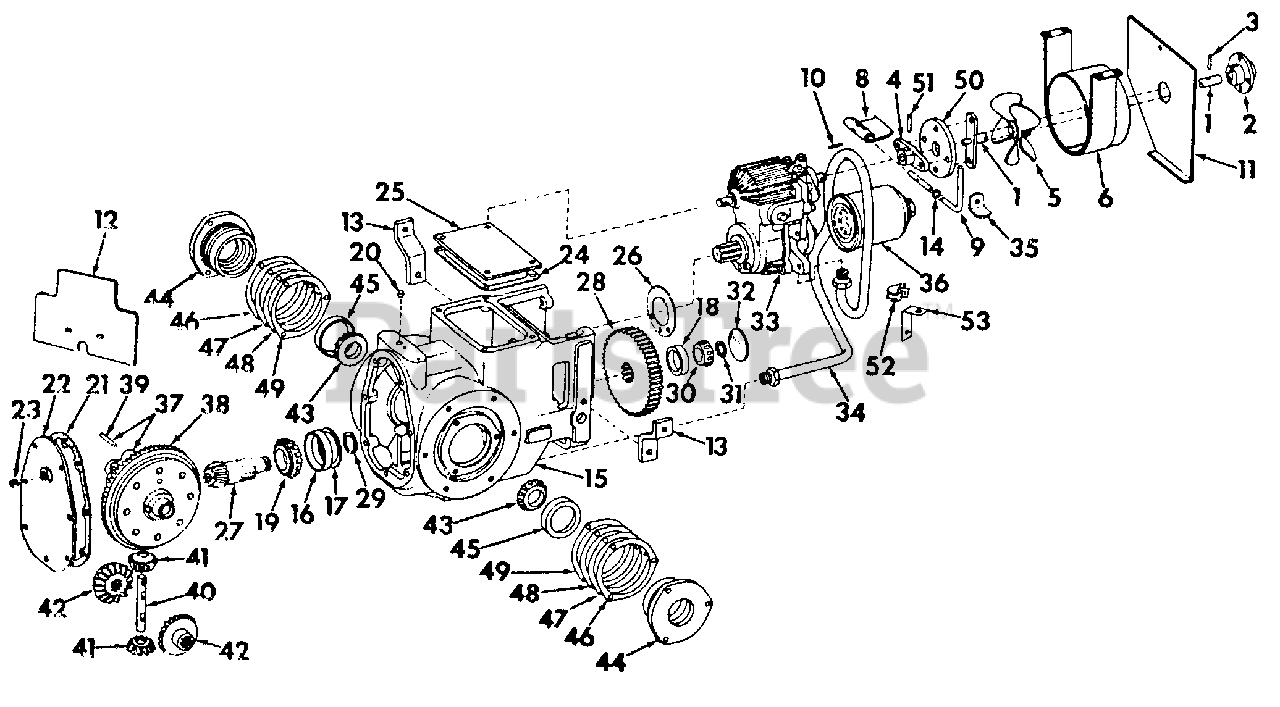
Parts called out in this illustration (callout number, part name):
1	Rod Assy, Drive
2	Hub Assy, Drive Plate
3	Pin, 1/4 X 1-1/2 Dowel
4	Arm, Coupling
6	Shroud Assy, Fan
8	Actuator, Dump Valve
9	Rod, Dump Valve
10	Pin, 1/8 X 3/4 C-Z Hv Coiled Spring
11	Plate, Air Baffle
12	Shield, Transmission Case Rear Cover
13	Bracket, Transmission Mounting
14	Grommet, Dump Valve Rod
15	Case Assy, Transmission
16	Bearing, Bevel Pinion Shaft Rear Cup
17	Shim, Rear Brg Cup, .004
18	Bearing, Bevel Pinion Shaft Front Cup
19	Bearing Assy, Bevel Pinion Shaft Rear Cone
20	Plug, Transmission Breather
21	Gasket, Transmission Case Rear Cover Plate
22	Plate Assy, Transmission Case Rear Cover
23	Plug, 1/2-14 Automotive Sq-Soc-Hd Drain
24	Gasket, Transmission Case Top Cover
25	Cover, Transmission Case Top
26	Gasket, Transmission Case Front
27	Shaft, Bevel Pinion
28	Gear, Constant Mesh-66T
29	Ring, Gear Retaining
30	Bearing Assy, Bevel Pinion Shaft Front Cone
31	Ring, Pinion Shaft Front Brg Retainer, .125
31	Ring, Pinion Shaft Front Brg Retainer, .119
31	Ring, Pinion Shaft Front Brg Retainer, .113
31	Ring, Pinion Shaft Front Brg Retainer, .107
31	Ring, Pinion Shaft Front Brg Retainer, .101
31	Ring, Pinion Shaft Front Brg Retainer, .131
32	Plug, 2-1/8 in. Expansion
33	Transmission Assy, Hydrostatic Drive
34	Tube w/Nuts, Suction
35	Bracket, Lever Retaining
36	Filter Assy
37	Case Assy, Differential
38	Gear, Differential Drive -46T
39	Pin, Differential Pinion shaft Lock
40	Shaft, Differential Pinion
41	Pinion, Differential - 10T
42	Gear, Differential Side
43	Bearing Assy, Differential Cone
44	Cage Assy, Differential Brg
45	Bearing, Differential Cup
46	Shim, Differential Brg retainer, .004
47	Shim, Differential Brg Retainer, .007
48	Shim, Differential Brg Retainer, .0149
49	Shim, Differential Brg Retainer, .0299
50	Disc, Flexible Coupling
51	Pin, 1/4 x 1-1/2 Hv Coiled Spring
52	Clip, Suction Tube
53	Bracket, Suction Tube
